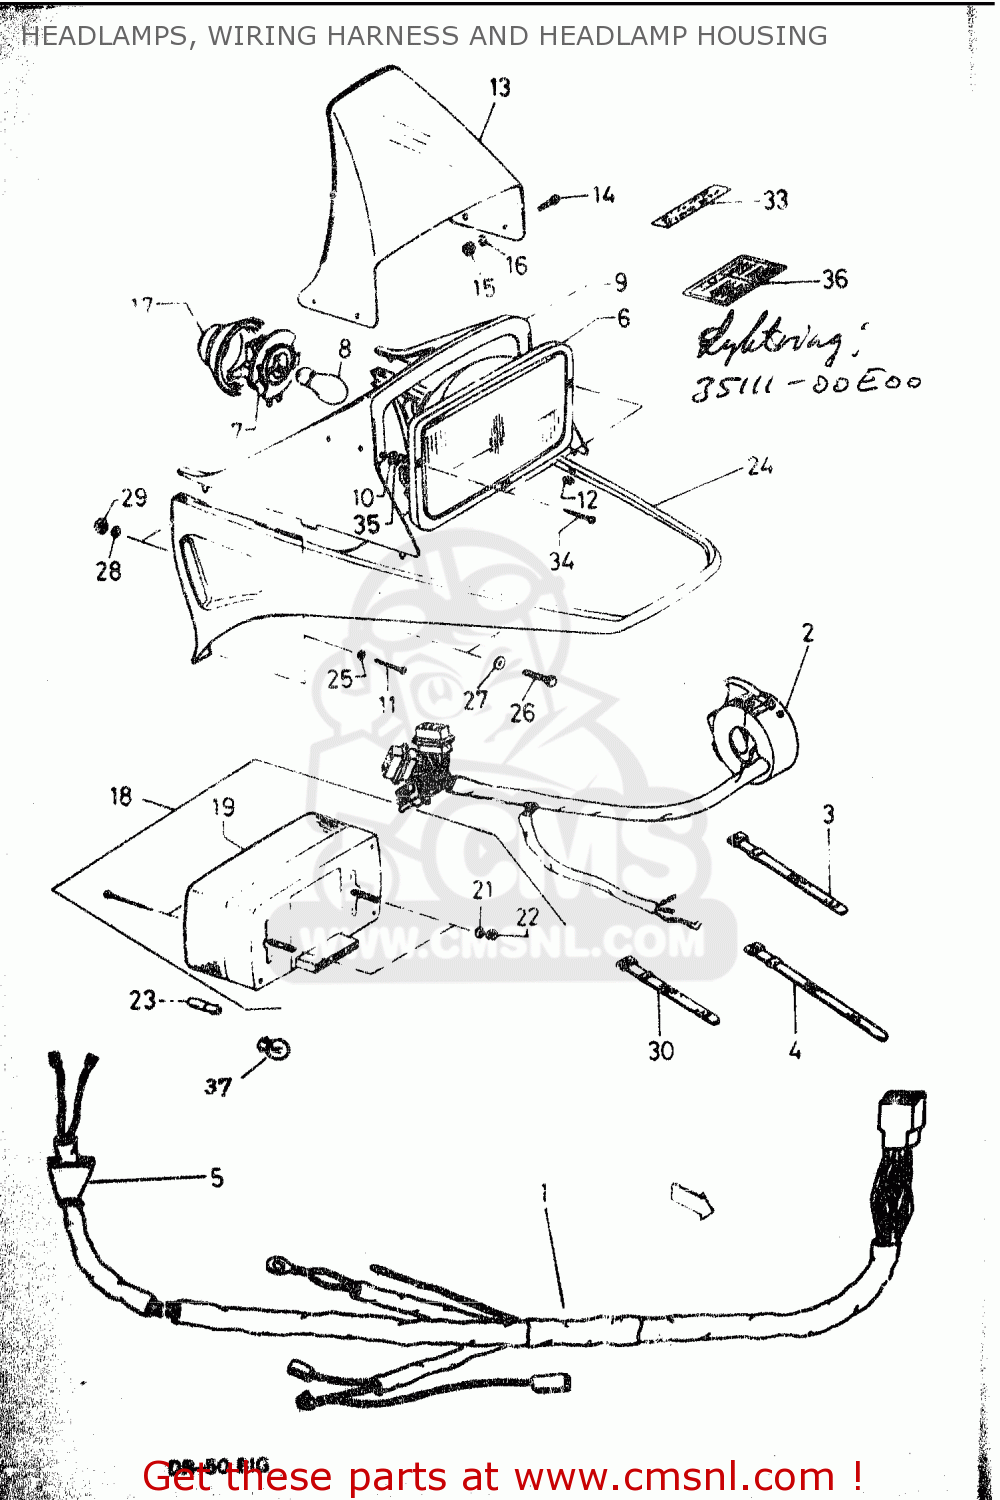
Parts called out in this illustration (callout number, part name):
1	HARNESS, WIRING
2	WIRING SWITCH
3	CLAMP L=138
4	CLAMP L=170
5	CAP
6	UNIT, HEADLAMP ONHE WITHOUT BULB
7	SOCKET
8	BULB (12V-25/25W)
9	WINDOW UNIT LAMP
10	NUT (NUL 522 4C)
11	SCREW 3.5X13 DIN 7981
12	NUT
13	VISOR, METER
14	SCREW M5X10 DIN 7985/N
15	NUT M5 DIN 934/N
16	WASHER A5 DIN 137/N
17	COVER SOCKET
18	LAMP ASSY, REAR COMBINATION WITHOUT BULB
19	LENS
21	LOCK WASHER
22	NUT
23	BULB (12V-4W)
24	COWLING, FRONT (BLUE)
25	WASHER B4 DIN 125
26	SCREW M5X15 DIN 933
27	WASHER 5 DIN 9021
28	WASHER B135 DIN 125
29	NUT
30	CLAMP
33	EMBLEM HELMET
34	SCREW 3.5X19 DIN 7981
35	BUSH
36	LABEL, TIRE AIR PRESSURE
37	BULB (12V-10W)
